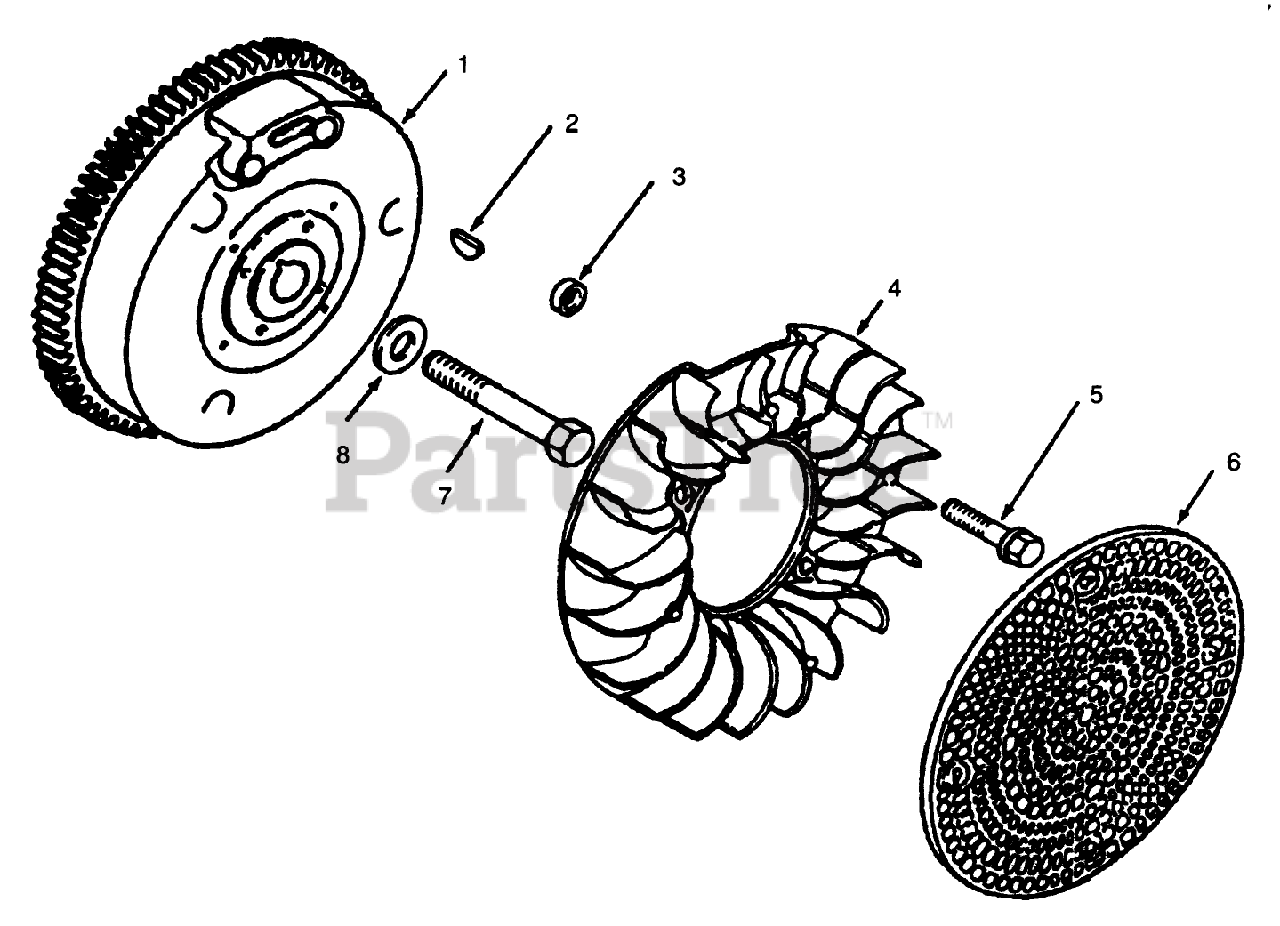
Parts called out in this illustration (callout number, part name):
1	KOHLER 47-025-53
2	KOHLER X-46-3
3	KOHLER 41-100-01
4	KOHLER 25-157-01
5	KOHLER 25-086-21
6	KOHLER 25-162-01
7	KOHLER 25-086-24
8	KOHLER 52-468-15
